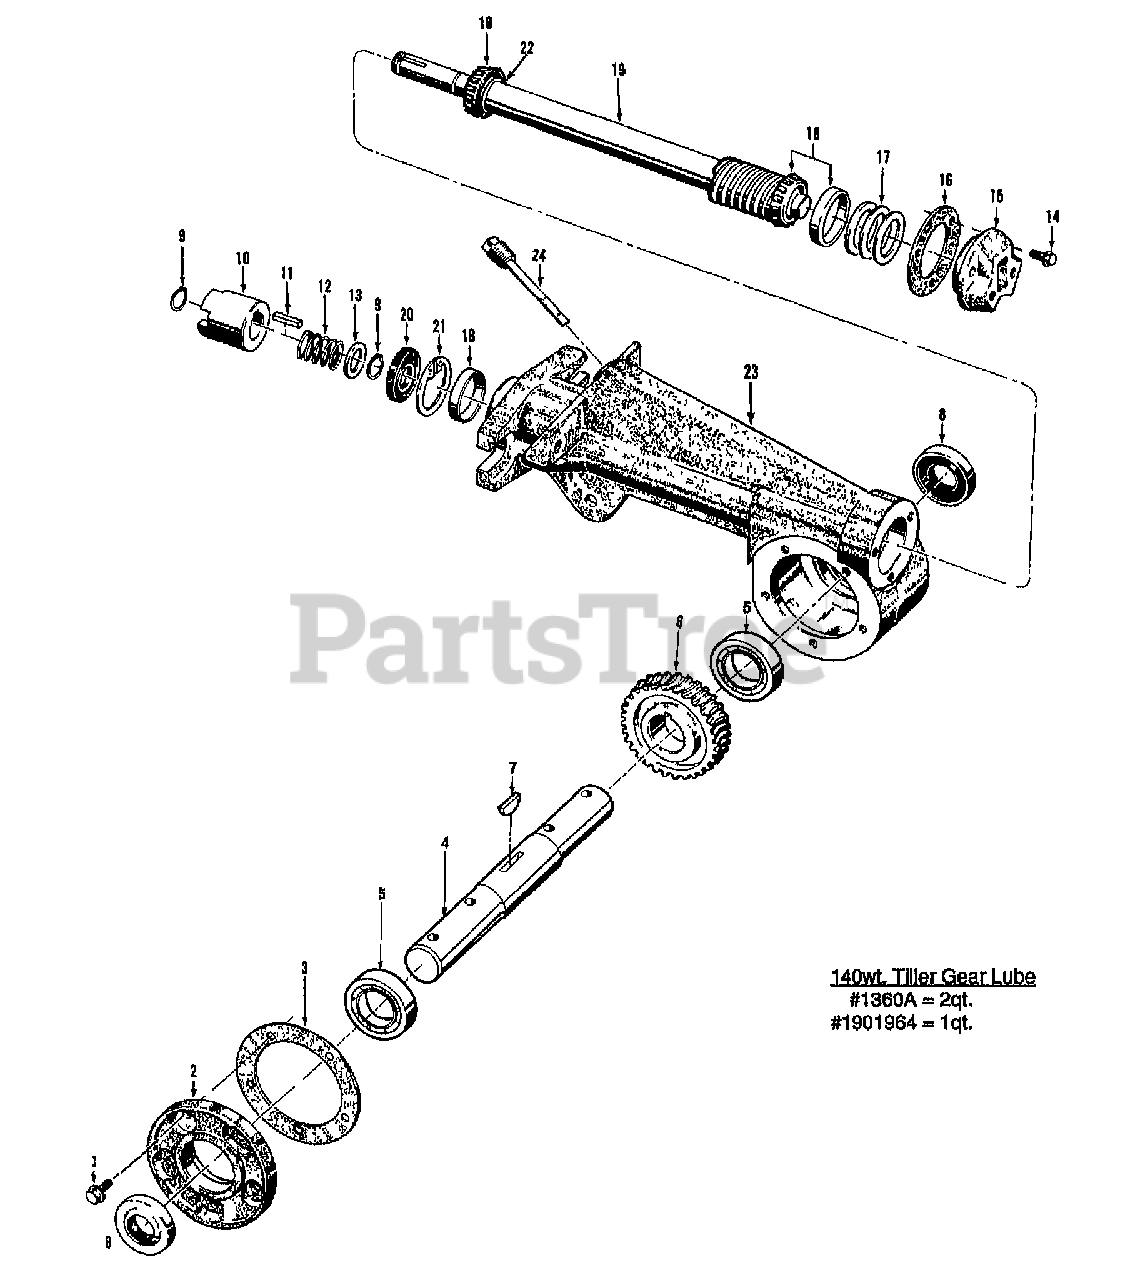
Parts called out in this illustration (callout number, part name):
1	KIT-SEALING SCRS (5)W/LIT
2	COVER-TILLER HSG MACH
3	GASKET-TILLER COVER
4	SHAFT-TILLER MACH HORSE
5	BEARING-BALL
6	GEAR-WORM MACH RTH HORSE
7	KEY-WOODRUFF .25X1.12
8	SEAL-TILLER SHAFT
9	RING-RETAIN EXT .707 ID
10	KIT-CLUTCH DOGS TILLER
10	CLUTCH-DOG HORSE TRANS
11	KEY-.188 SQX1.0
12	SPRING (TC)
13	SHIM-1.0X.7656X.062
14	KIT-SEALING SCRS (3)
15	CAP-REAR #1115
16	GASKET-BRG COVER
17	SHIM-1.75X1.5X.01
17	SHIM-1.75X1.5X.03
17	SHIM-1.75X1.5X.005
17	SHIM-1.75X1.5X.062
18	KIT-BRG CONE&RACE-DRIVESHAFT
19	KIT-TILLER DR SHAFT
20	SEAL-OIL DRIVESHAFT
21	RING-RETAINING 5000-181
22	SHIM-1.0X.7656X.062
23	HOUSING-TILLER W/SLEEVE
24	ASSM-DIPSTICK HORSE TRANS
